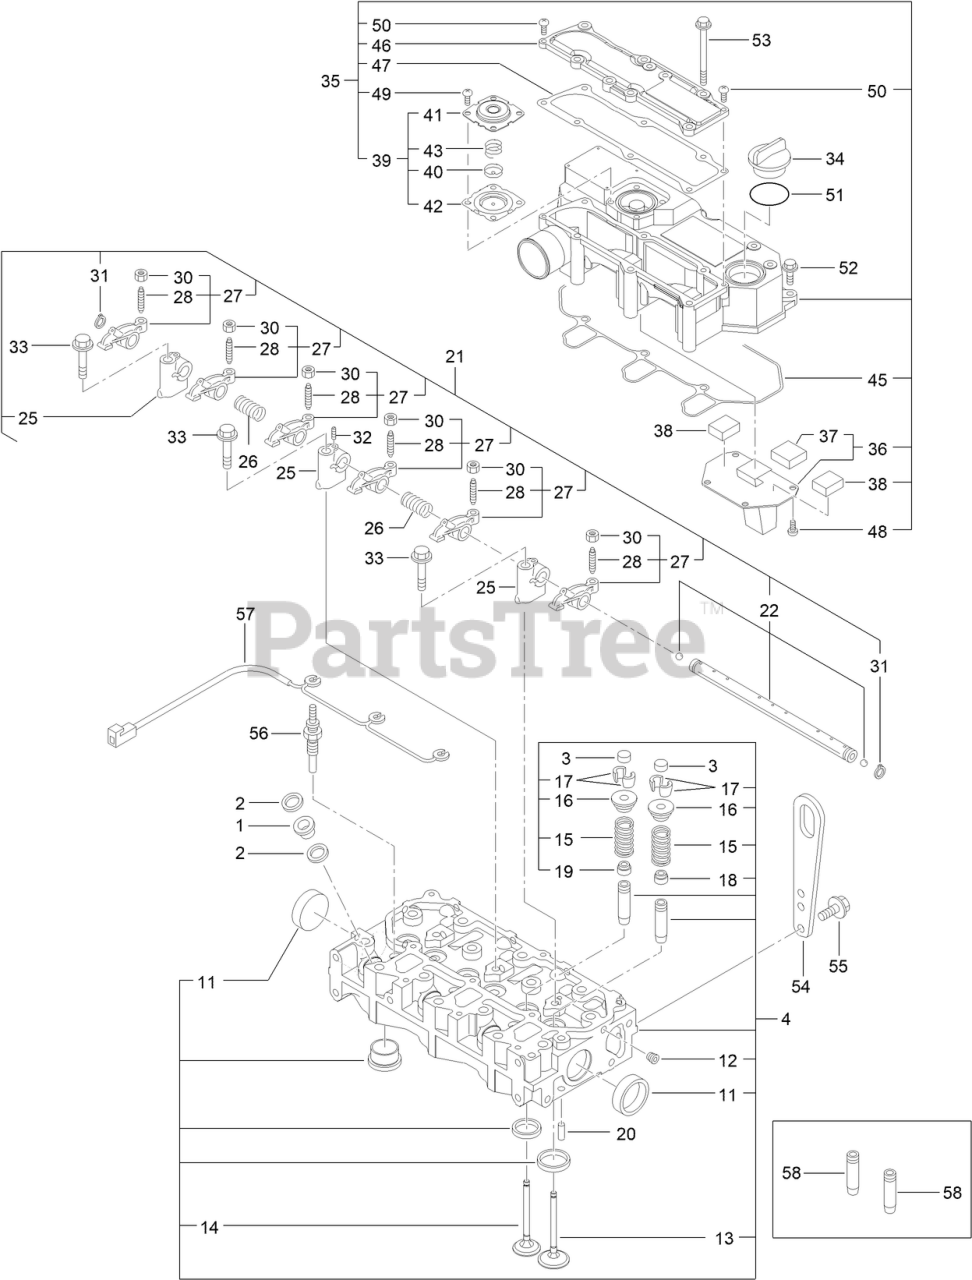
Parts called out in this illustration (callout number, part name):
1	PROTECTOR-NOZZLE
2	GASKET-NOZZLE
3	CAP-VALVE
4	CYLINDER HEAD ASM
11	PLUG-CUP
13	VALVE-SUCTION
14	VALVE, EXHAUST 3
15	SPRING-VALVE
16	RETAINER
17	COTTER
18	SEAL-STEM, VALVE
19	SEAL-STEM, VALVE
20	PIN-SPRING
21	SUPPORT ASM-ROCKER
22	SHAFT ASM-ROCKER
25	SUPPORT-ROCKER ARM
26	SPRING-ROCKER
27	ARM ASM-ROCKER
28	SCREW-ADJUST, VALVE
34	COVER-FILLER
35	CYLINDER HEAD COVER ASM
36	PLATE-BAFFLE
37	BAFFLE-BREATHER
38	BAFFLE-BREATHER
39	DIAPHRAGM ASM
40	PLATE-DIAPHRAGM
41	COVER-DIAPHRAGM
42	DIAPHRAGM
43	SPRING-DIAPHRAGM
45	GASKET-BONNET
46	COVER-HEAD, CYLINDER
47	GASKET
51	O-RING
54	LIFTER, ENGINE
56	PLUG-GLOW
57	CONNECTOR-PLUG, GLOW
